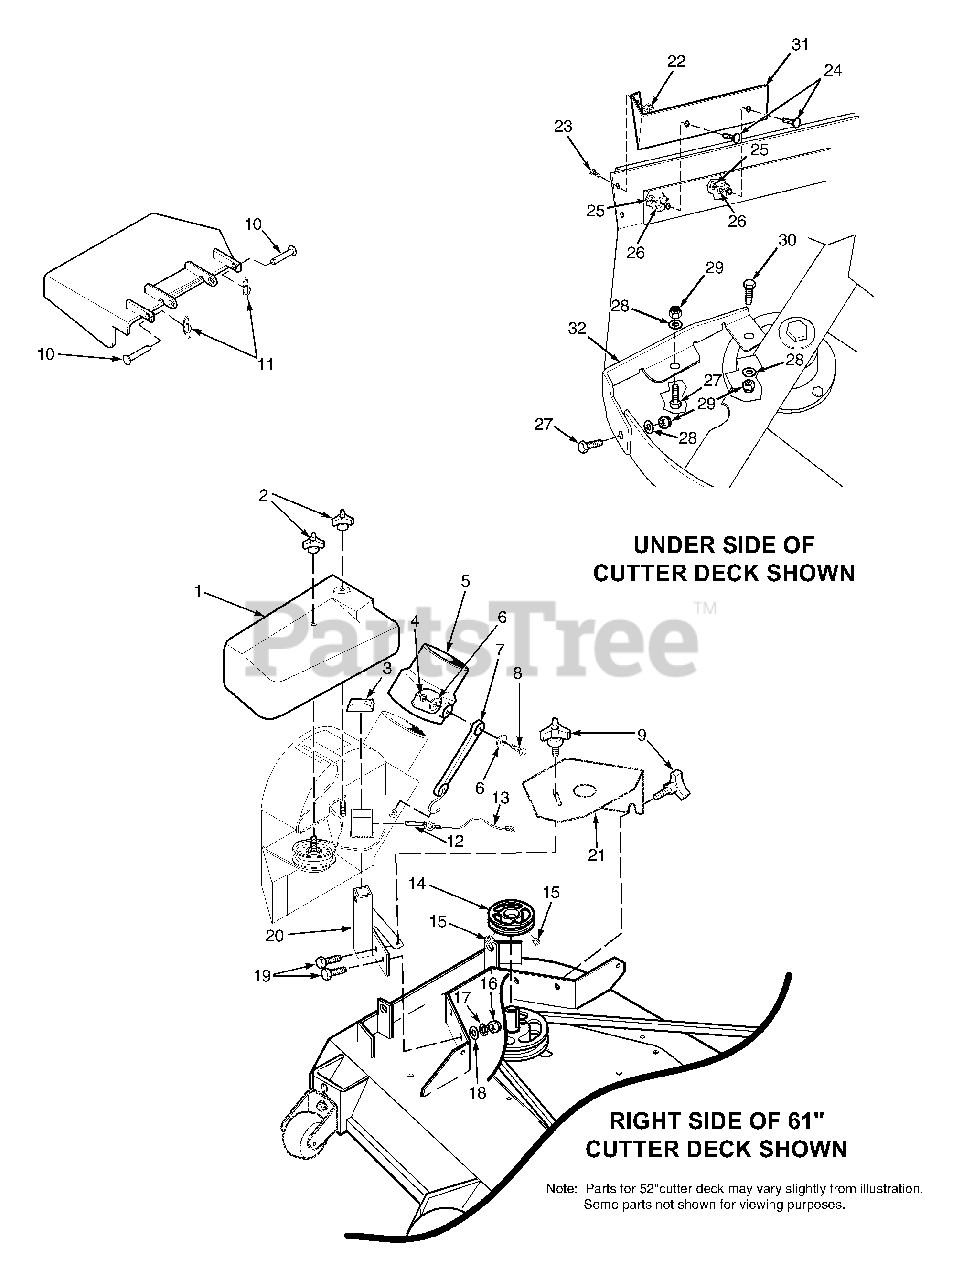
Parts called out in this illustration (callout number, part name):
1	Belt Cover, GC-STT - 52"
2	Wingnut, Plastic 3/8 Small
3	Cap, Square Vinyl
4	Nut, Elastic Stop 1/4-20
5	Adapter, Blower GC-STT
6	Flatwasher, 1/4-.312 x .750 x .065
7	Rubber Strap 7-3/4"
8	Bolt, Hex Head 1/4-20 x 1-1/4"
9	Knob W/Stud, 3/8-16 x 1-1/4"
10	Clevis Pin, 5/16 x 1-1/2"
11	Pin, Rue Cotter 5/16 Dia.
12	Pin, Ring 1/2 x 2-1/4"
13	Lanyard
14	Pulley, 4-1/2" for 52" Deck
15	Setscrew, 5/16-18 x 3/8"
16	Nut, Elastic Stop 1/2-13
17	Lockwasher, 1/2"
18	Flatwasher, 1/2-.531 x 1.062 x .095
19	Bolt, Hex Head 1/2-13 x 1-1/2" Grade 5
20	Mounting Post Weldment, Blower - 52"
21	Belt Cover, - 52"
22	Nut, Serrated Flange 1/4-20
23	Bolt, Hex Head 1/4-20 x 3/4"
24	Bolt, Carriage 3/8-16 x 1"
25	Nut, Elastic Stop 3/8-16
26	Flatwasher, 3/8-.391 x .938 x .105
27	Bolt, Hex Head 5/16-18 x 1"
28	Flatwasher, 5/16-.375 x .875 x .083
29	Nut, Elastic Stop 5/16-18
30	Bolt, Hex Head 5/16-18 x 1-3/4"
31	Baffle, 52"
32	Baffle, 52" Deck
